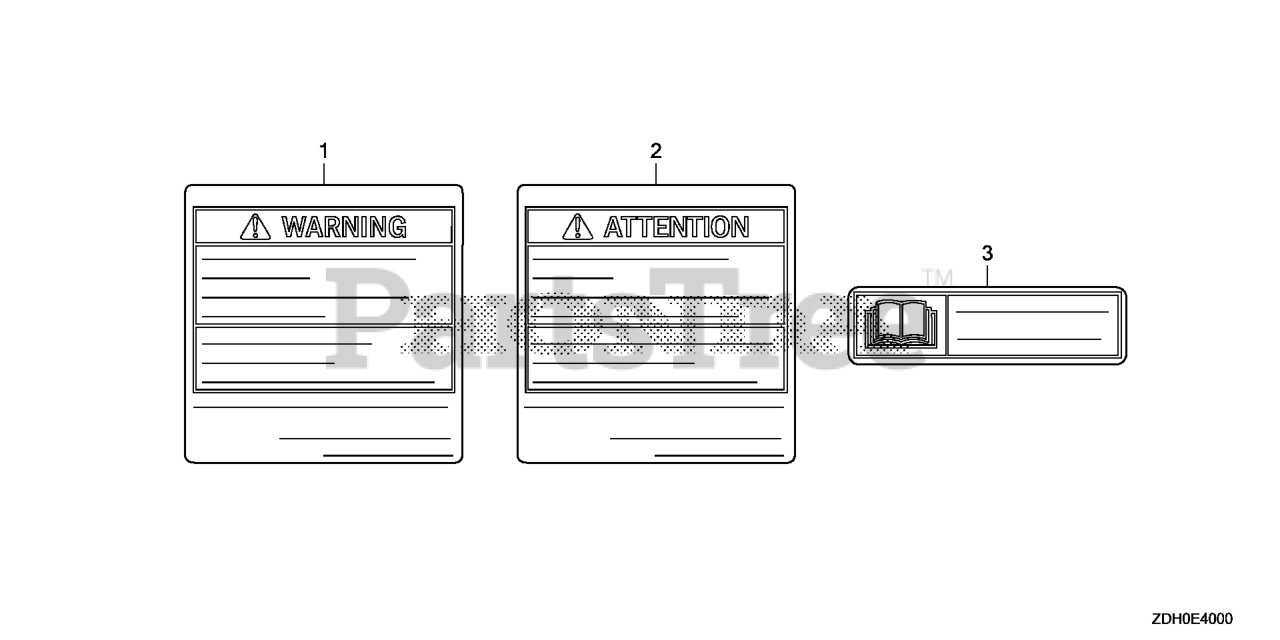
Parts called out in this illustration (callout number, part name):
1	MARK, OPER CAUTION
2	MARK, OPER CAUTION
3	LABEL, CAUTION (CHINA)
